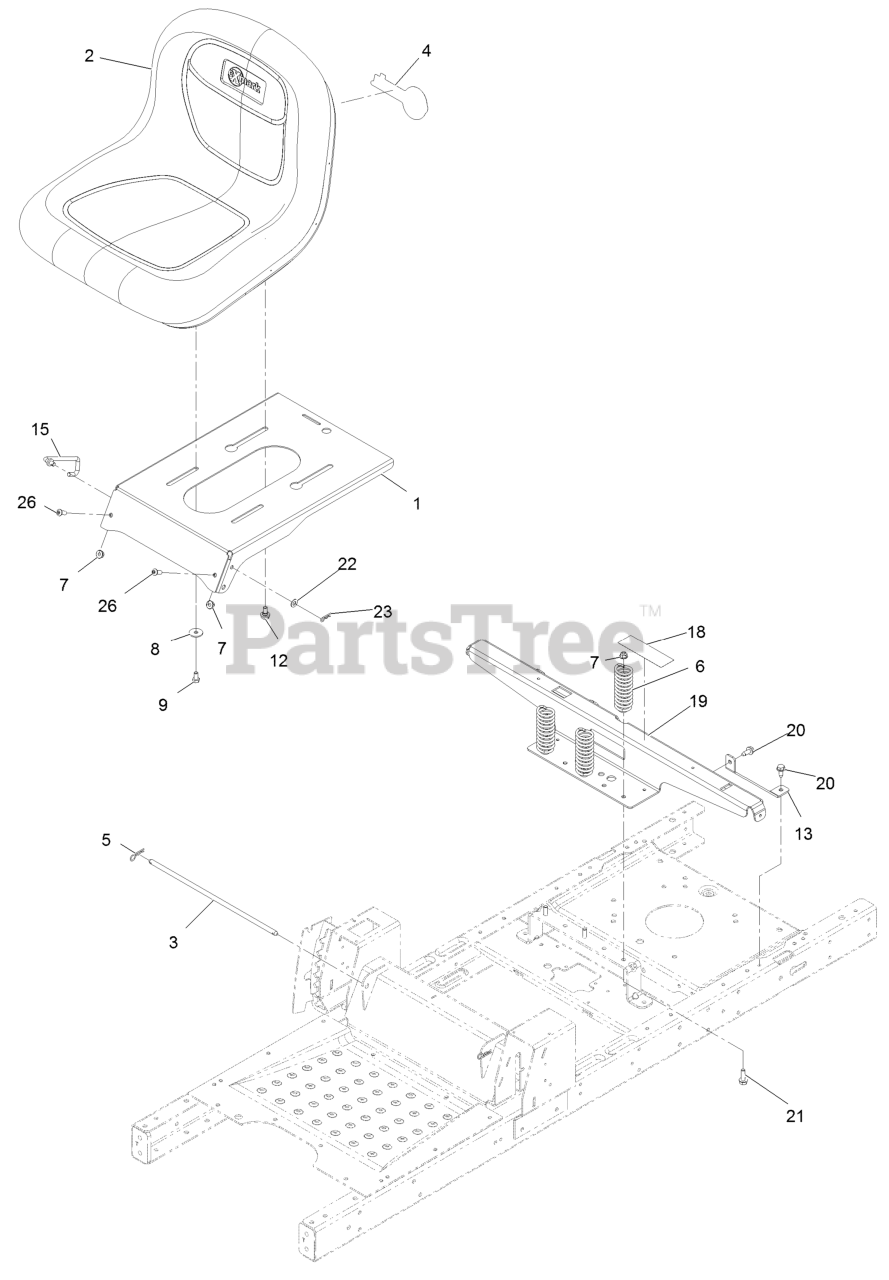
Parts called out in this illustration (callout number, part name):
2	SEAT-15 IN
3	ROD-PIVOT, NARROW
4	DECAL-EXMARK LOGO
5	PIN-COTTER
6	SPRING-COMPRESSION
7	NUT-HF, NI
8	WASHER-PIVOT
9	SCREW-HH
12	BOLT-SHOULDER,HFH
13	SUPPORT-TANK, REAR
15	STOP-SEAT
18	DECAL-SERVICE, CE
19	SUPPORT-POD
20	Screw-HWH 5/16-18 X 3/4 Tf
21	SCREW-HHF
22	WASHER-PLAIN
26	SCREW-HSBH
